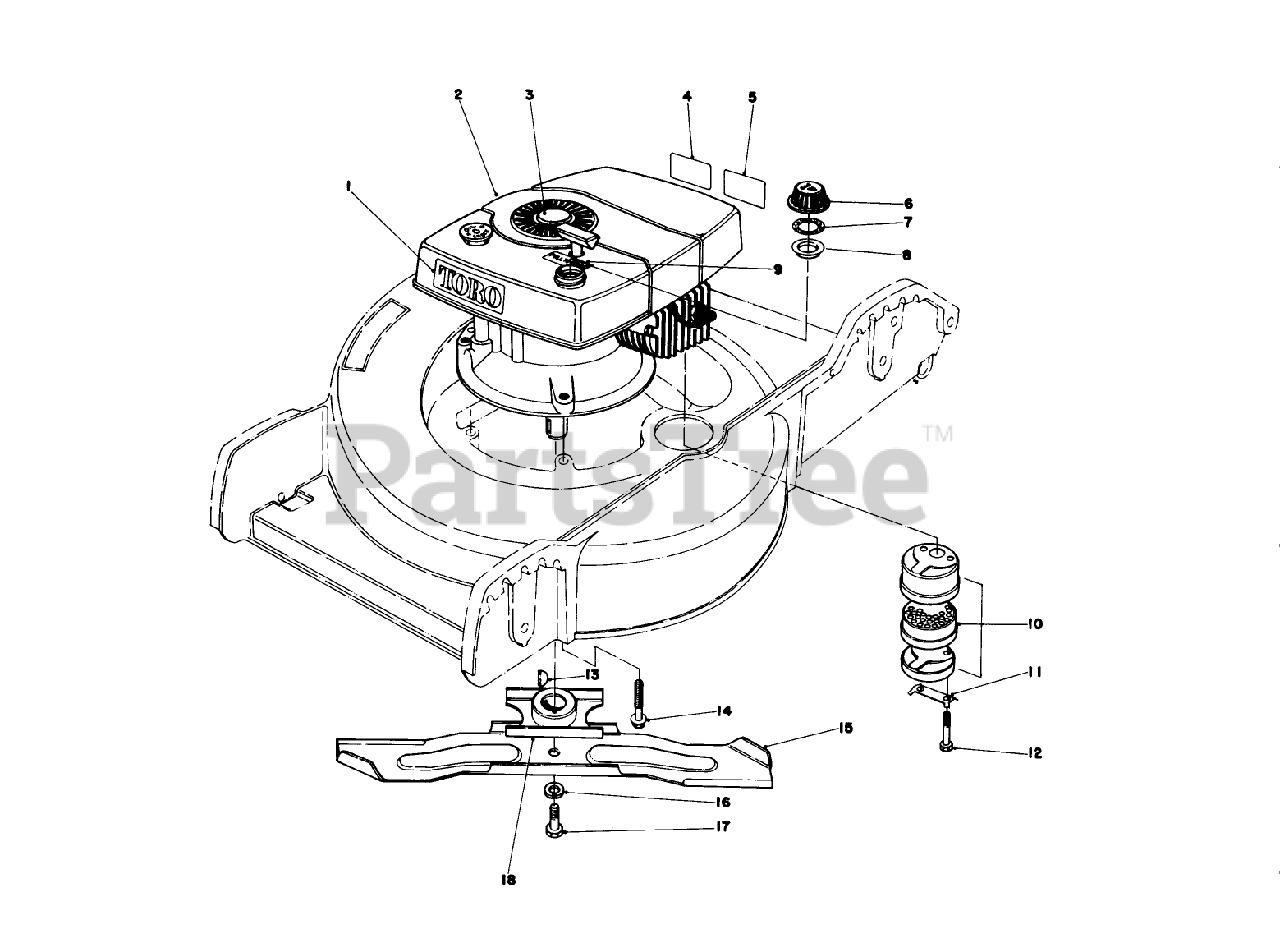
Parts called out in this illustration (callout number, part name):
1	Decal Toro
2	Engine
3	Plug Button
4	Decal-Maintenan
5	Decal Maintenance
6	Gas Cap (Incl. Ref. #7 & 8)
7	GASKET
8	GAS CAP BAFFLE
9	Decal Pull
10	Muffler (Incl. Ref. #11 & 12)
11	CLIP - LOCKING
12	SCREW-HH
13	KEY-WOODRUFF
14	3/8-16 X 2 CAPSCREW
15	Blade
16	WASHER-LOCK
17	SPECIAL SCREW
18	Blade Retailer
